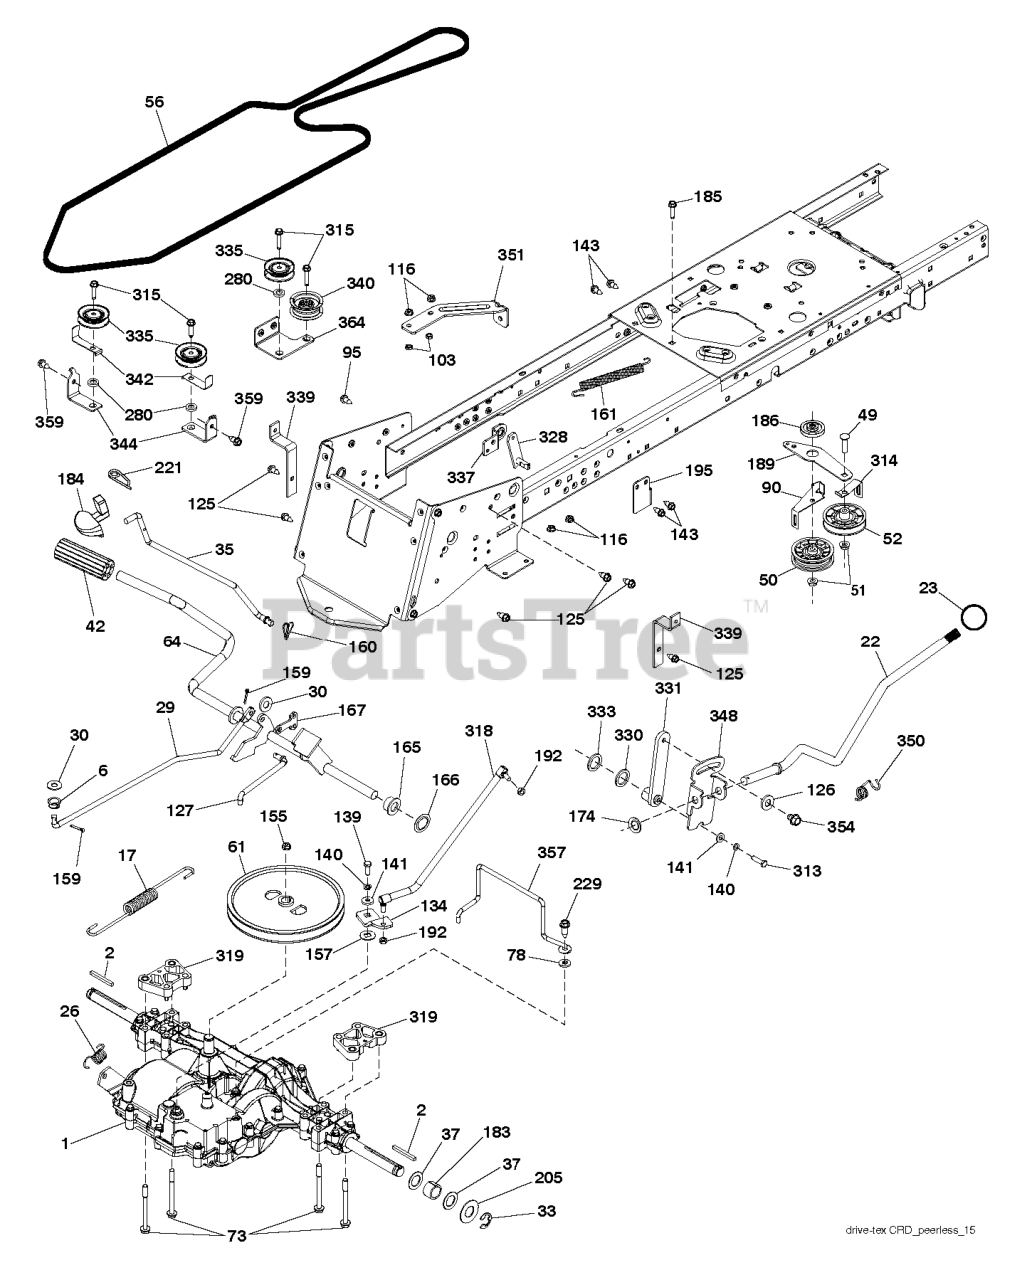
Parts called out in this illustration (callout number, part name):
2	SQUARE KEY
6	MANDREL ASS'Y
17	SPRING SPRING BRAKE GEAR CRD
22	ROD ROD SHIFT CRD TEX
23	KNOB.DUCKHEAD.1/2
26	SPRING,BRAKE RETURN
29	ROD.BRAKE.GEAR.CRD.TEX
30	WASHER
35	ROD.CNTRL.PARK.PREDATOR.LT.TEX
42	PEDAL COVER T
45	LOCKNUT.NYLOC.1/4-20
48	BOLT.3/8-16X1.50
51	NUT LOCK FLG 3/8-16 UNC
56	BELT BELT V CRD GEAR
61	PULLEY
64	SHAFT.ASM.PEDAL.BRAKE.
73	BOLT.HEX.FLNG.5/16-18X3.75
90	BRACKET KEEPER BELT CLUTCHING
95	SCREW, 3/8-16X3/4
103	JAM NUT TI
116	NUT LOCK HEX FLANGE 5/16-18
124	BOLT.SHOULDER.5/16-18X
125	SCREW
126	WASHER.SRRTD.5/16
127	RP.LINK.CLUTCH.GROUND.DRIVE
139	BOLT 1/4-28X3/4
140	LOCKWASHER
141	WASHER LT
143	SCREW LT
155	RETAINING RING LT
157	WASH-SHFT PLT LT
159	COTTER PIN
160	RETAINER CLIP
161	SPRING, RETURN LT
165	BUSHING.SHAFT.BRAKE.HAND
166	NUT.PUSH.625
167	LATCH.BRAKE.SPRING
183	SPACER AXLE
184	HANDLE.PARKING.BRK.PRED.LT.RED
186	SPACER.RETAINER
187	WASHER 12/32X2X10GA
189	BELLCRANK BELLCRANK GROUNDDRI
192	NUT LOCK CENTER 1/4 -28 FNTHD
221	RETAINER.SPRING.CLIP.H
229	SCREW 5/16-18X1
300	PULLEY.V-IDLER.
310	SCREW LT
313	BOLT
314	RETAIN BELT
315	BOLT.5/16-18X1.25
318	GEAR LINK SHIFT GEAR
319	SPACER SPACER TRANSAXLE TEX C
321	IDLER PULLEY
326	BOLT CARRIAGE
328	SHAFT SHAFT SHIFT FRONT
329	BRACKET.SHIFT.MOUNT
330	WASHER.NYL.7/8IDX.105"HYD CR
331	RB HUB.SHIFT
332	BOLT
333	WASHER.WAVE.SPRING
337	BRACKET BRACKET SUPT SHIFT CR
339	STRAP STRAP TORQUE K46 CRD TE
340	IDLER.FLAT.2.25.INCH
342	BELT GUIDE
343	WASHER T
344	BRACKET BRACKET IDLER CRD TEX
348	BRACKET.PIVOT.LEVER
349	WASHER
350	SHIFT SPRING
351	BRACKET BRACKET DECK SWAY
354	CAPSCREW.HXHD.FLG.5/16-18X.625
357	KEEPER KEEPER
